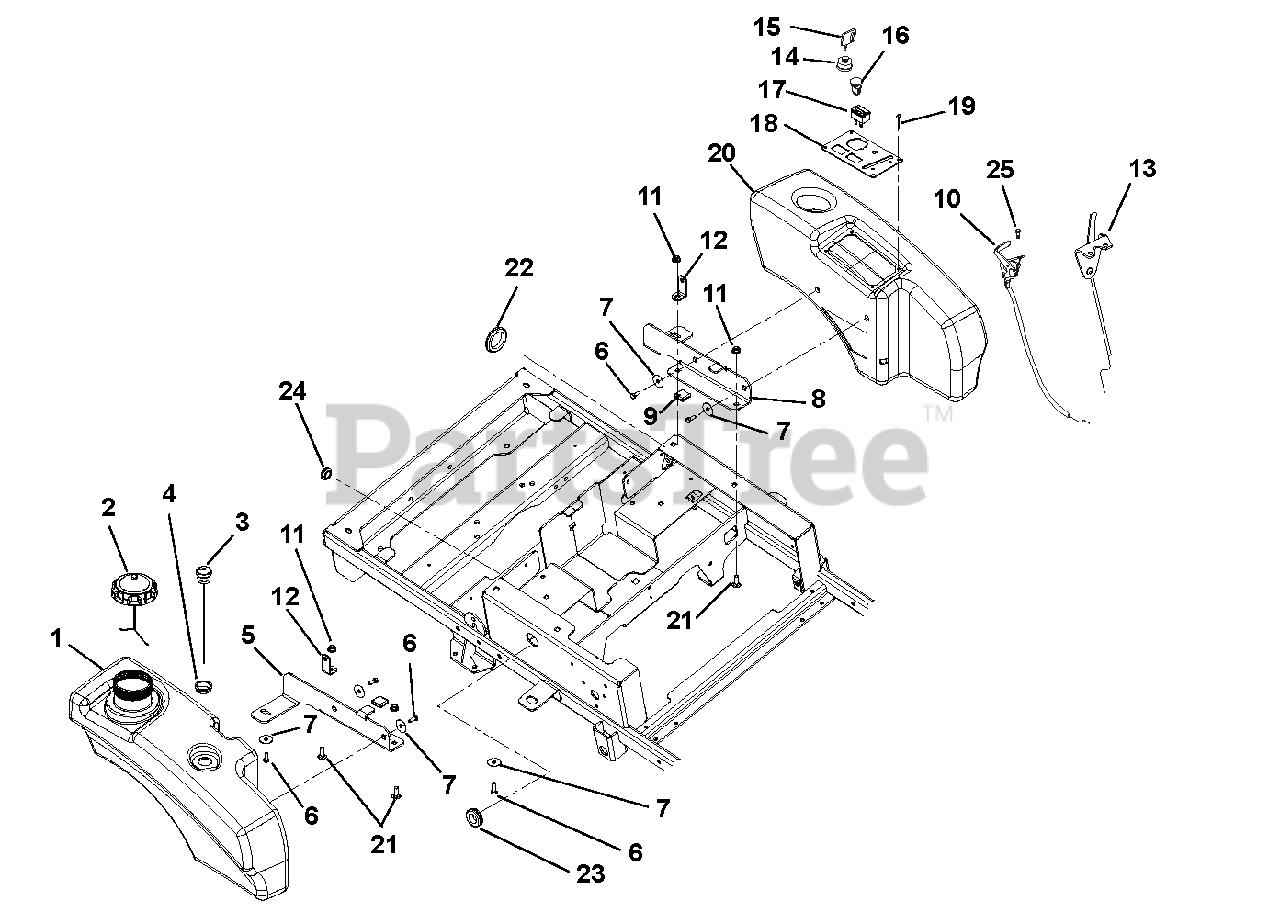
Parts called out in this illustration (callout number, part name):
1	TANK, XL
2	CAP, FUEL
3	GAUGE, REMOTE FUEL 10.0"
4	GROMMET, FUEL GAGE
5	BRKT, RH REAR TANK MOUNT
6	BLT-SERHFWH .312-18X.50 YWZC
7	WSHR-FL-STL .347X1.254X.048YWZ
8	BRKT, LH REAR TANK MOUNT
9	GRIP, RUBBER (1.0X1.0X.187)BLK
10	CABLE-THROTTLE
11	@NUT-LK-NYL-FLG .38-16 YWZC
12	BRKT, HOOD PIVOT
13	CABLE, CHOKE
14	KEY SWITCH
15	KEY -W/CAP
16	SWITCH, CLUTCH
17	HOUR METER - DIGITAL
18	CONTROL PANEL
19	RIVET, PLASTIC .195 DIA.
20	FENDER, XL
21	@BLT-RDHDSQNK .38-16X1.00 G5YZ
22	GROMMET 1.70ID X 2.0OD
23	GROMMET 1.0ID X 1.38 OD
24	GROMMET,RUBBER 5/8 ID/1.13 OD
25	@SCR-TAP 10-24X.50 HWH TR YWZC
